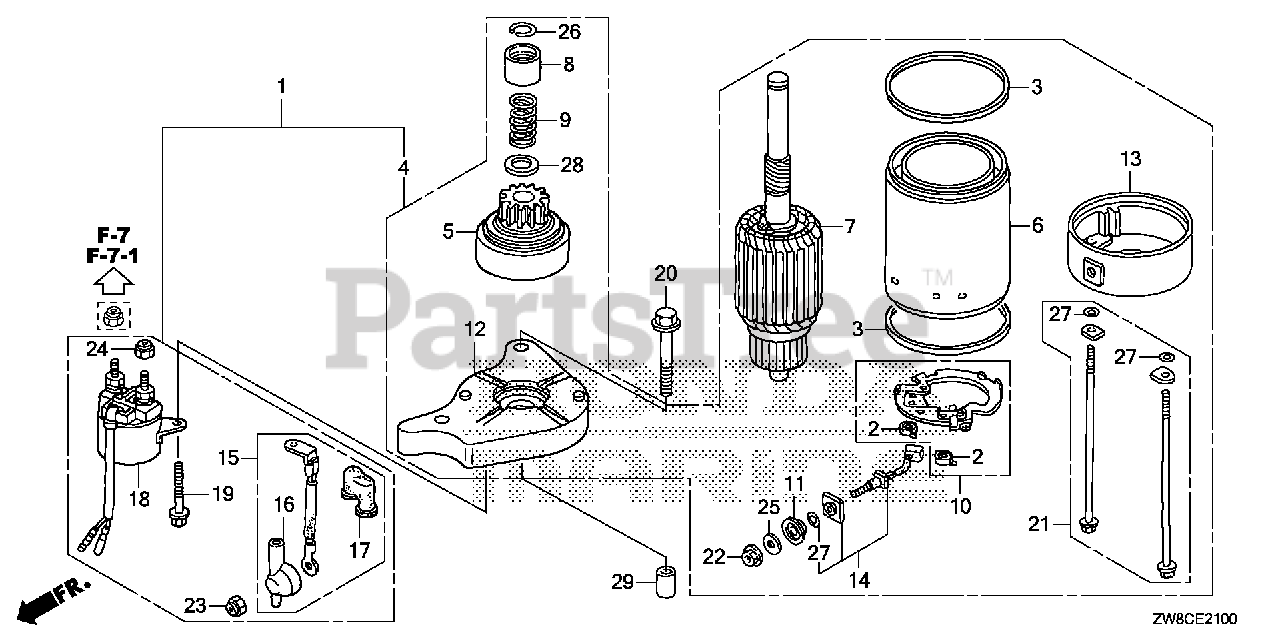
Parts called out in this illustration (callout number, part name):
1	MOTOR ASSY., STARTER
2	SPRING, CARBON BRUSH
4	MOTOR UNIT, STARTER
8	PIECE, STOPPER
9	SPRING, RETURN
10	HOLDER, BRUSH
12	BRACKET, FR.
13	BRACKET, RR.
14	UNIT, TERMINAL
15	WIRE, MAGNETIC SWITCH
16	COVER, STARTER TERMINAL
17	COVER, MAGNETIC SWITCH TERMINAL
18	SWITCH ASSY., STARTER MAGNETIC
19	BOLT, FLANGE (6X14)
20	BOLT, FLANGE (8X45)
21	BOLT, SETTING
22	NUT-WASHER (6MM)
23	NUT, LOCK (6MM)
24	NUT, LOCK (6MM)
25	WASHER (6MM)
26	CIRCLIP (14MM)
27	O-RING
29	PIN, DOWEL (10X12)
